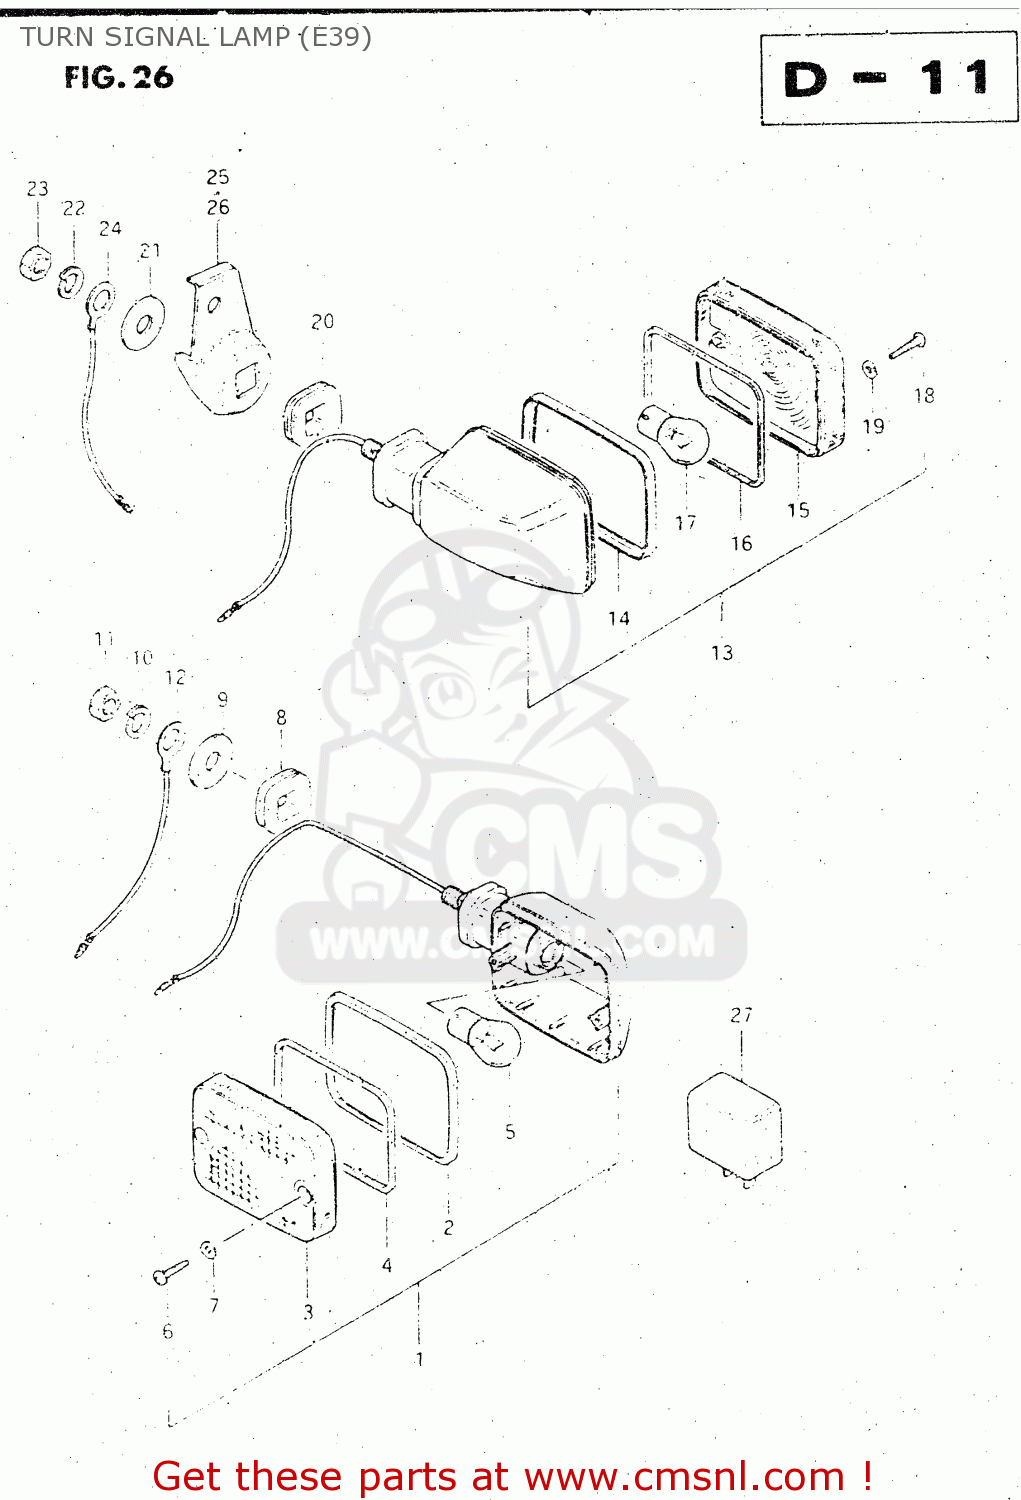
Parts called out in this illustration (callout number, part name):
1	LAMP, FRONT TURN SIGNAL
2	RIM
3	LENS
4	GASKET (NAS)
5	BULB 12V 21W
6	SCREW
7	GASKET (NAS)
8	CUSHION
9	WASHER (10.5X30X2.3)
10	LOCK WASHER
11	NUT
12	WIRE
13	LAMP, REAR TURN SIGNAL
14	RIM
15	LENS
16	GASKET (NAS)
17	BULB 12V 21W
18	SCREW
19	GASKET (NAS)
20	CUSHION
21	WASHER (10.5X30X2.3)
22	LOCK WASHER
23	NUT
24	WIRE
25	BRACKET,REAR TURN SIGNAL
26	BRACKET,REAR TURN SIGNAL
27	RELAY,TURN SIGNAL
